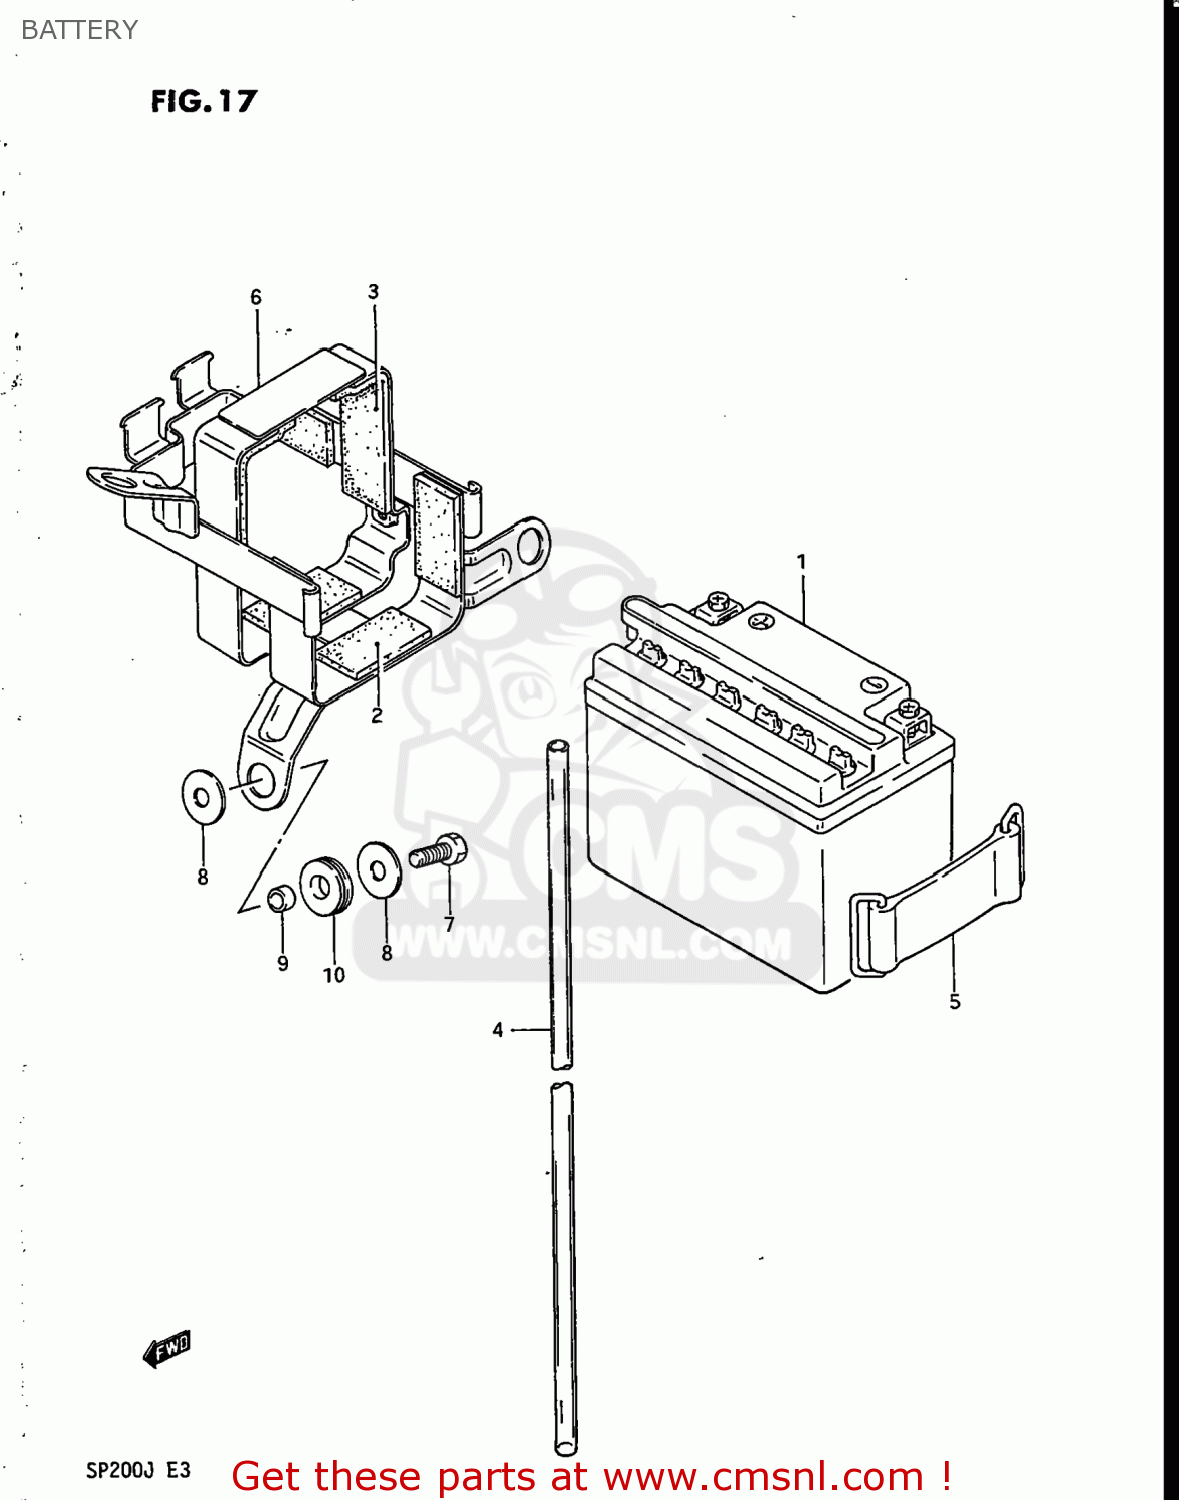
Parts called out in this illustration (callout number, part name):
1	BATTERY ASSEMBLY
2	PROTECTOR,BATTERY
3	PROTECTOR,20X9
4	HOSE,BATTERY EXHAUST
5	BAND
6	HOLDER,BATTERY
7	BOLT
8	WASHER (6.5X20X1.2)
9	SPACER (6X9X5)
10	CUSHION
